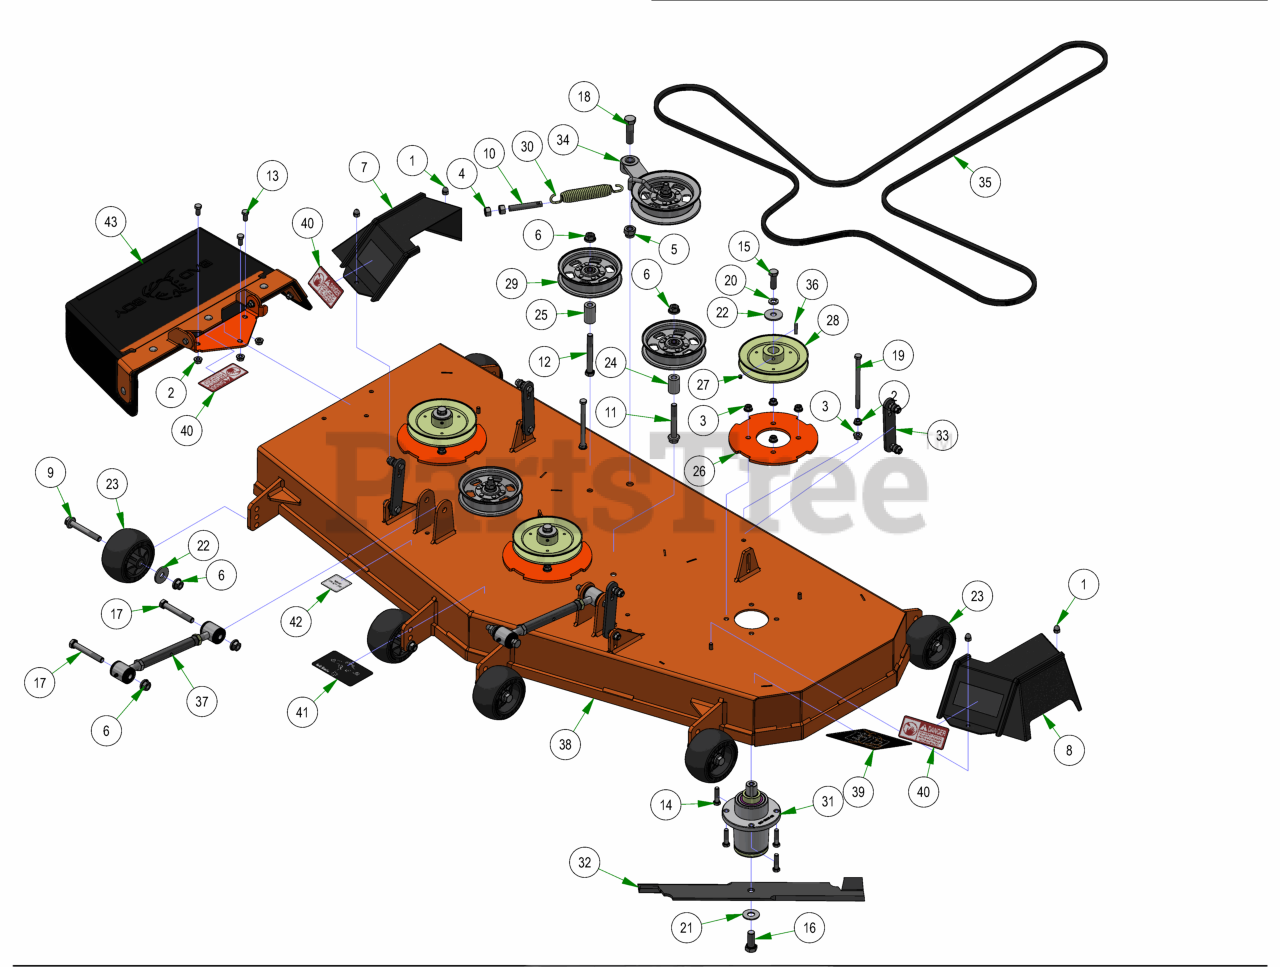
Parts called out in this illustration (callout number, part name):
1	5/16-18 ACORN NUT HIGH-CROWN ZC
2	3/8-16 HEX SERRATED FLANGE NUT HARD/ZINC
3	3/8-16 NYLON INSERT FLANGE LOCKNUT (GR.F) ZINC
4	1/2-13 HEX NUT ZINC
5	5/8-11 NYLON INSERT LOCKNUT ZINC
6	1/2-13 NYLON INSERT FLANGE LOCKNUT ZINC
7	2021 Maverick 54”/60” RH Pulley Cover
8	2021 Maverick 54”/60” LH Pulley Cover
9	1/2-13 X 90MM HEX FLANGE BOLT W/SHOULDER (GR.8) ZINC
10	All Thread
11	1/2-13 X 3-1/2 HEX FLANGE BOLT (GR.8) ZINC
12	1/2-13 X 4 HEX CAP SCREW (GR.8) ZINC YELLOW
13	3/8-16 X 3/4 HEX CAP SCREW (GR.5) ZINC
14	3/8-16 X 1-1/2 HEX CAP SCREW (GR.5) ZINC
15	1/2-20 X 1-1/2 HEX CAP SCREW (GR.5) ZINC
16	5/8-18 X 1-1/2 HEX CAP SCREW (GR.8) ZINC YELLOW
17	1/2-13 X 3-1/2 HEX CAP SCREW (GR.5) ZINC
18	5/8-11 X 2-1/4 HEX CAP SCREW (GR.5) ZINC
19	3/8-16 X 5-1/2 HEX CAP SCREW (GR.5) ZINC
20	1/2 SPLIT LOCKWASHER (GR.8) ZINC/YELLOW
21	5/8 USS FLAT WASHER (1-3/4" OD) GR.8 ZINC YELLOW
22	1/2 BELLEVILLE WASHER (1-5/8 OD X .140 THK) ZINC
23	Deck Wheel
24	.502 ID X .750 OD X 1.500 Long Spacer
25	1 3/4" Pulley Spacer
26	Deck Spindle Support Plate
27	5/16-24 X 1/4 SOCKET SET SCREW (CUP PT) PLAIN
28	6 1/4" Drive Pulley
29	5-3/4 Idler Pulley
30	Deck Idler Spring
31	Spindle Assembly
32	60" High Lift Fusion Blade
33	Deck Hanger Assembly
34	Maverick HD & Down Deck Idler Assembly
36	1/4 X 1 SQ MACHINERY KEY 1018 STL PLN
37	2018 Maverick Turnbuckle (Top Link)
38	2025 60" x 5" Deck
39	60" Grip Deck Decal
40	Danger Decal-Spindle/Discharge
41	Deck Belt Route Decal
42	Deck Impact Patent Decal 9591803
43	Discharge Chute Assembly
